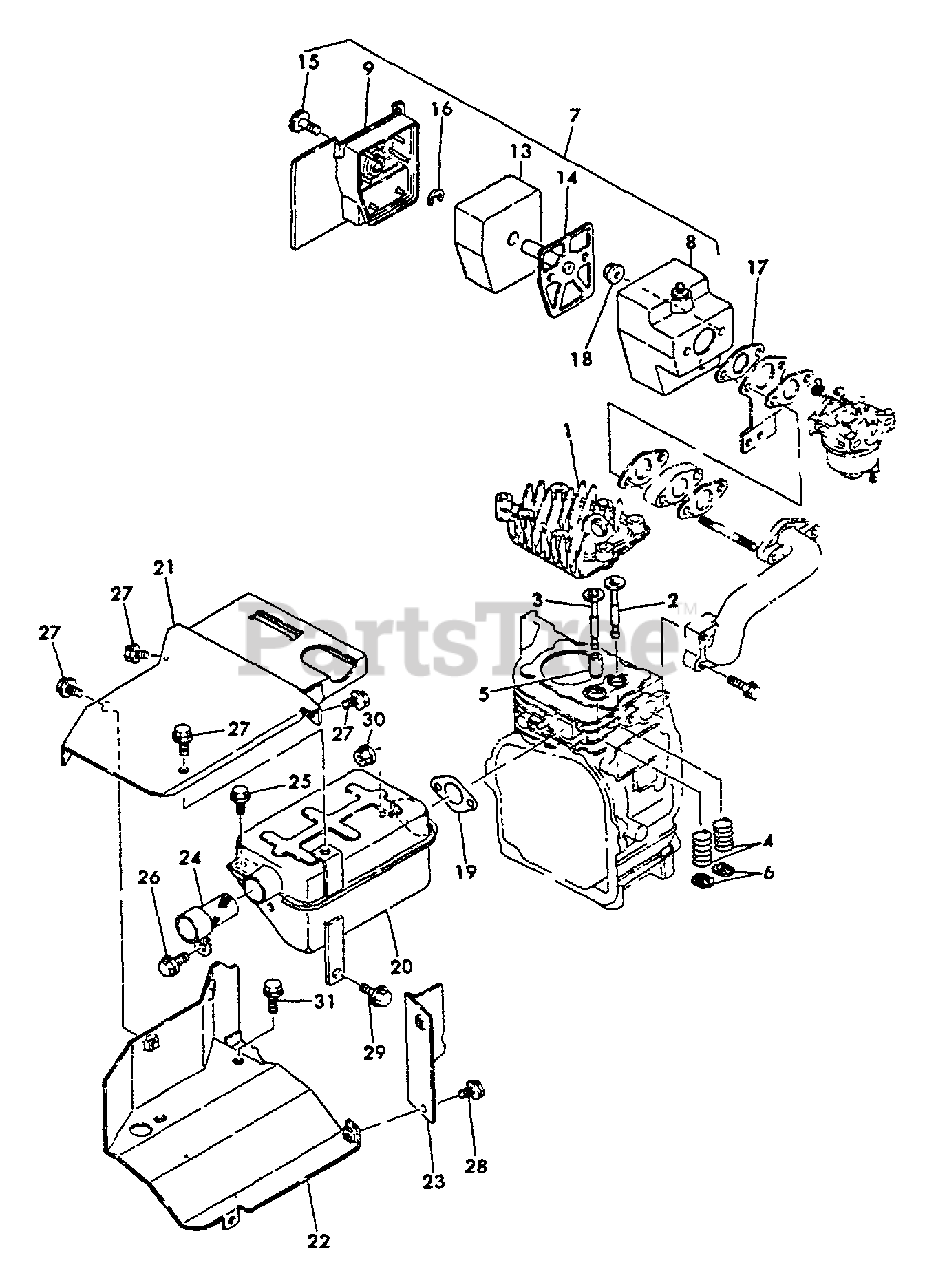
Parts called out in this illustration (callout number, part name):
1	HEAD, CYLINDER
2	INLET, VALVE
3	VALVE, EXHAUST
4	SPRING, VALVE
5	GUIDE, VALVE
6	RETAINER, VALVE
7	AIR FILTER ASSY
8	CASE, AIR FILTER
9	COVER, AIR FILTER
13	FILTER, AIR
14	HOLDER, ELEMENT
16	RING, RETAINING - 5
17	GASKET
18	U-NUT M6
19	GASKET, EXHAUST
20	SILENCER
21	COOLING GUIDE (A)
22	COOLING GUIDE (B)
23	COOLING GUIDE (C)
24	ARRESTOR, SPARK
25	BOLT - 6×8 -- PLATED
26	BOLT - 6×8 -- PLATED
27	BOLT - 6×8 -- PLATED
28	BOLT - 6×8 -- PLATED
29	BOLT - 6×12 -- PLATED
30	U-NUT - 6
31	BOLT - 6×8 -- PLATED
